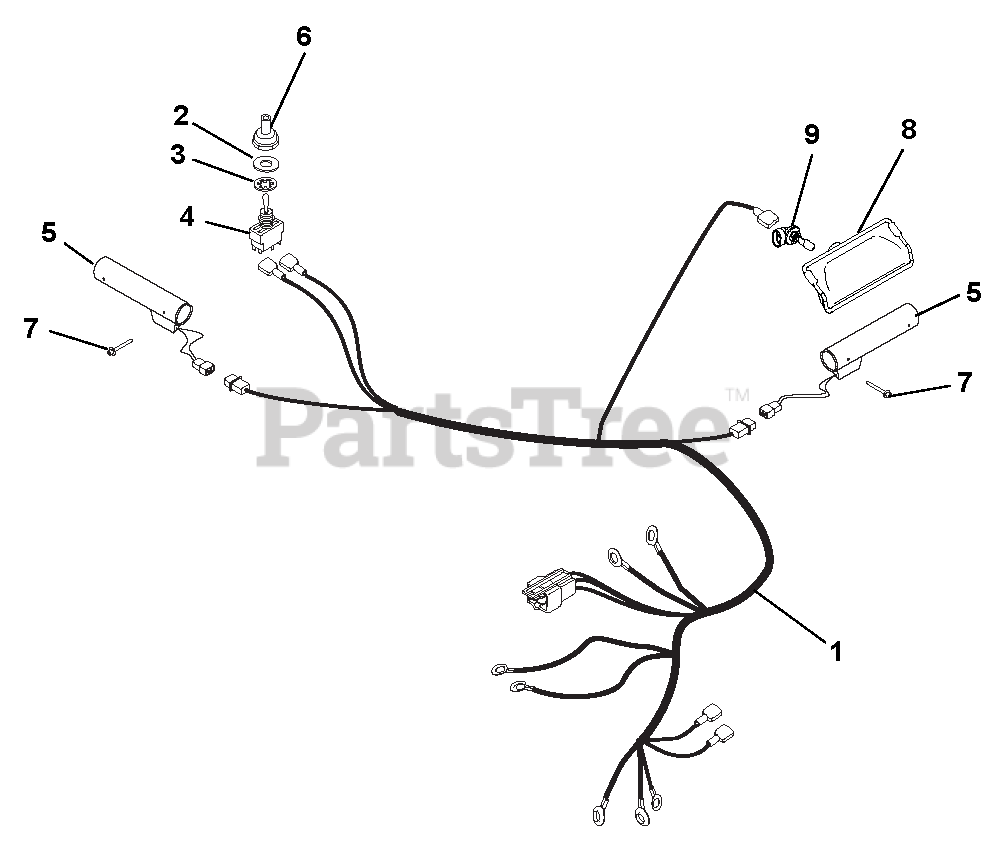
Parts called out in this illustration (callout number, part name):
1	HARNESS, LIGHT & WARMER
2	WSHR-FL-STL .505X.875X.024 PL
3	WSHR-LK-INT .563X.040 YWZC
4	SWITCH, ON/OFF
5	HEATED GRIP, MAGURA
6	BOOT, SWITCH
7	RVT-POP #43 .125X.313 STL ZINC
8	HEADLIGHT ASSY, HALOGEN 20W
9	BULB, LIGHT-HALOGEN 20W
